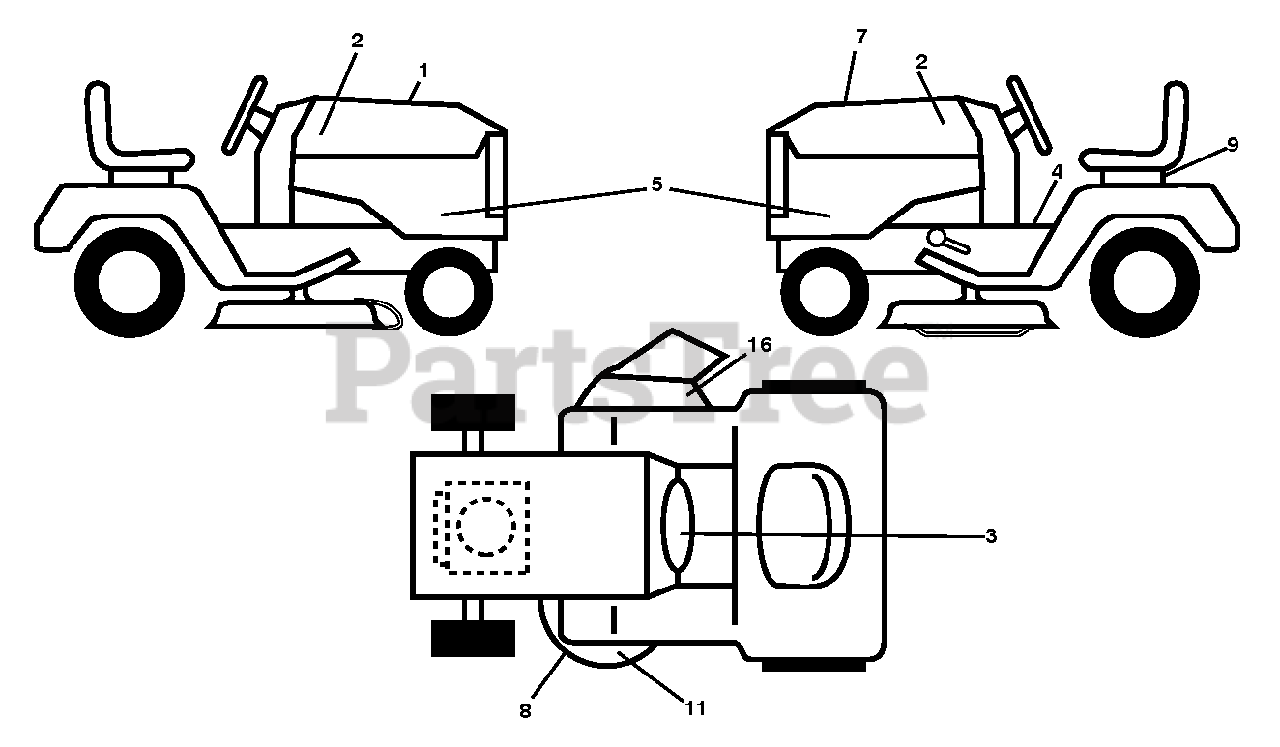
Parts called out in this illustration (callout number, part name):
2	DECAL.BADGE.170MM.TEXTLOGO.
3	DCL.WARNING.SPARK.IGNITION.CA
4	DECAL.WARNING.2007.ENG/FR
5	DECAL.SIDE.PANEL.YTA19K42
7	DECAL.WARNING.CUST.RESP.E85.
8	DECAL.V-BELT.SCH.42/46"MEC/ELE
9	DECAL BTRY SYMBOLS
11	DECAL POP ARMORPROTECTORDECK
16	DECAL, DECK DEFLECTOR, WARNING
